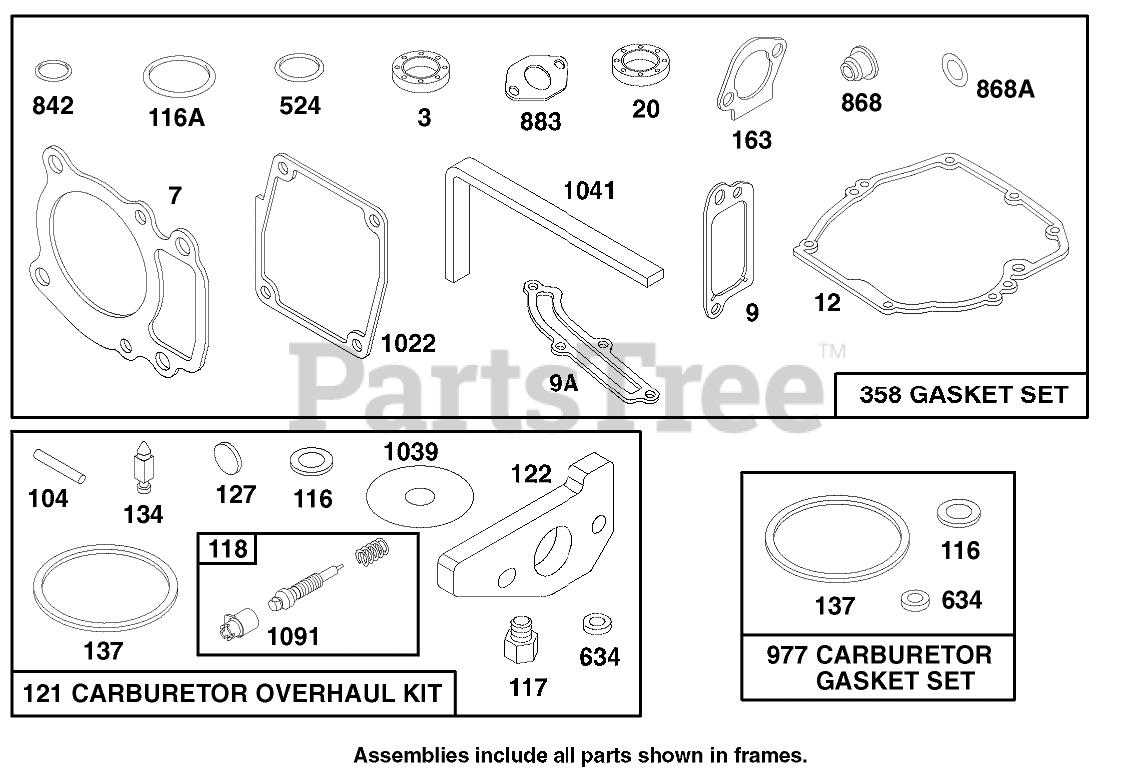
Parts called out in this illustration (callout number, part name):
3	SEAL - OIL
7	CYLINDER HEAD GASKET
9	BREATHER GASKET
9A	GASKET-BREATHER
12	ENGINE BASE GASKET
20	SEAL-OIL
104	FLOAT HINGE PIN
116	SEALING GASKET
116A	O RING SEAL
117	Jet-Main
118	VALVE/SPRING - NEEDLE
121	KIT-CARBURETOR OVERHAUL
122	ADAPTER ASSEMBLY
127	PLUG - WELCH
134	Valve-Inlet (Includes Seat)
137	FLOAT BOWL GASKET
163	AIR CLEANER GASKET
358	GASKET SET
524	O-RING
634	SEAL WASHER
842	O-RING
868	SealAssy-Valve
868A	Seal-Valve
883	EXHAUST GASKET
977	CARBURATOR GASKET SET
1022	ROCKER COVER GASKET
1039	FLOAT LIMITER
1041	SEAL - FOAM
1091	CAP - LIMITER
